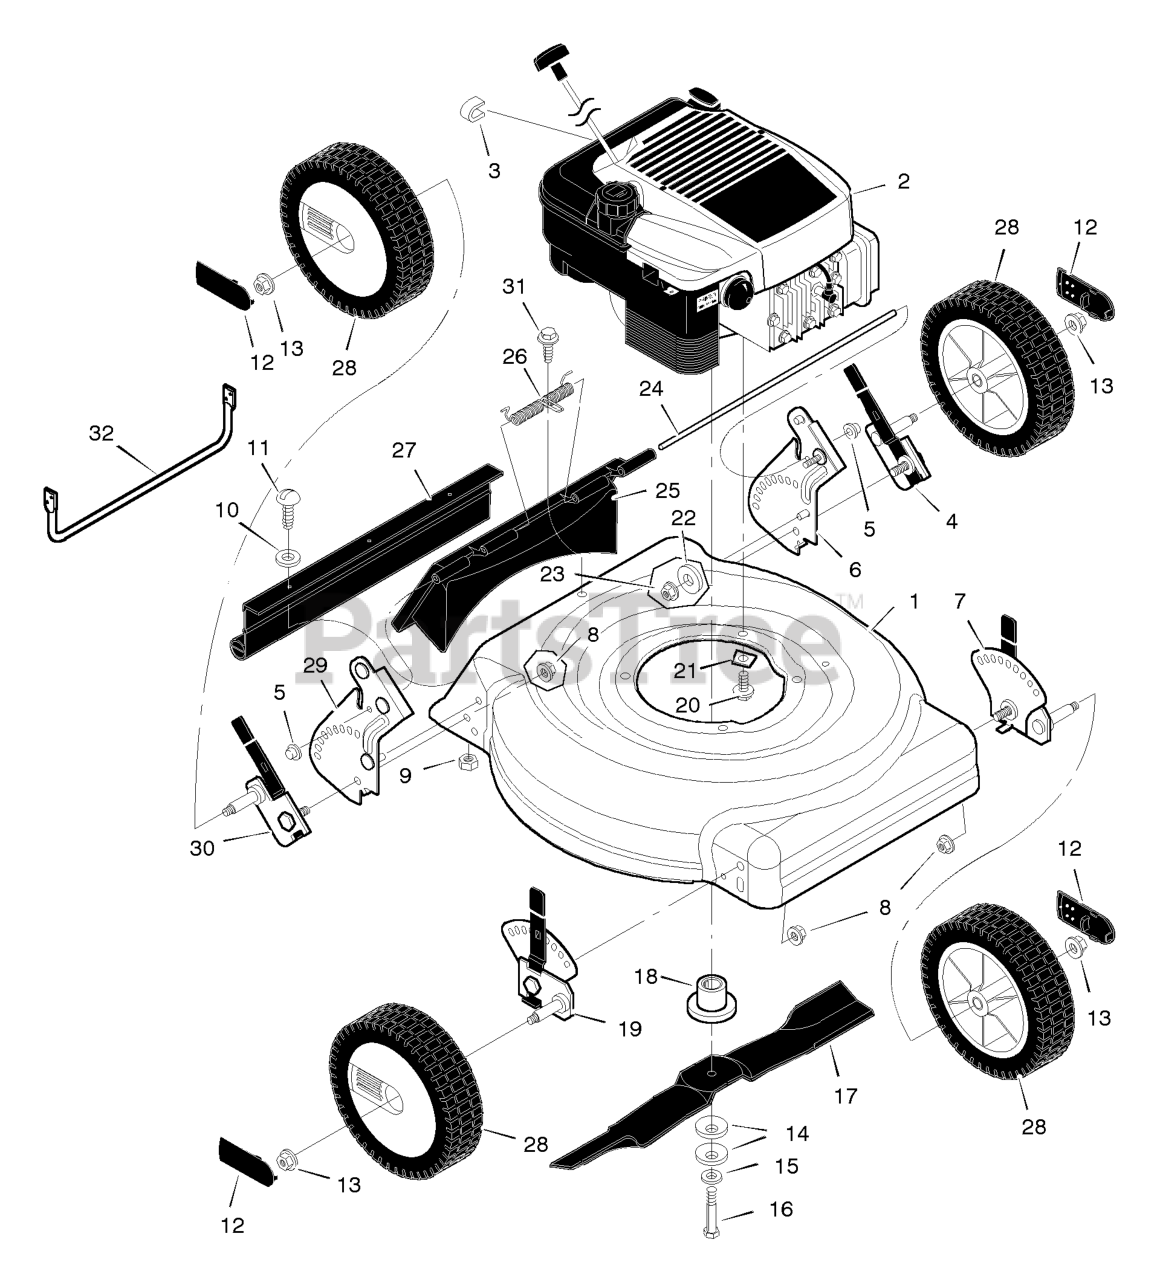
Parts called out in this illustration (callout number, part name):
1	Housing
2	Engine
3	Stop, Rope (Recoil - Start)
4	Adjuster, Left Height
5	Push On Cap
6	Bracket, Left Handle
7	Adjuster, Left Front Height
8	Nut, Flange
9	Nut, Hex
12	Hub Cap
13	Nut, Flange
14	Washer, Belleville
18	Adapter, Blade
19	Adjuster, Right Front Height
20	Bolt, Engine
21	Support, Engine
22	Washer
23	Nut, Flange
24	Rod, Pivot
25	Door, Rear
27	Deflector, Rear
29	Bracket, Right Handle
30	Adjuster, Right Height
32	Guard, Rear
